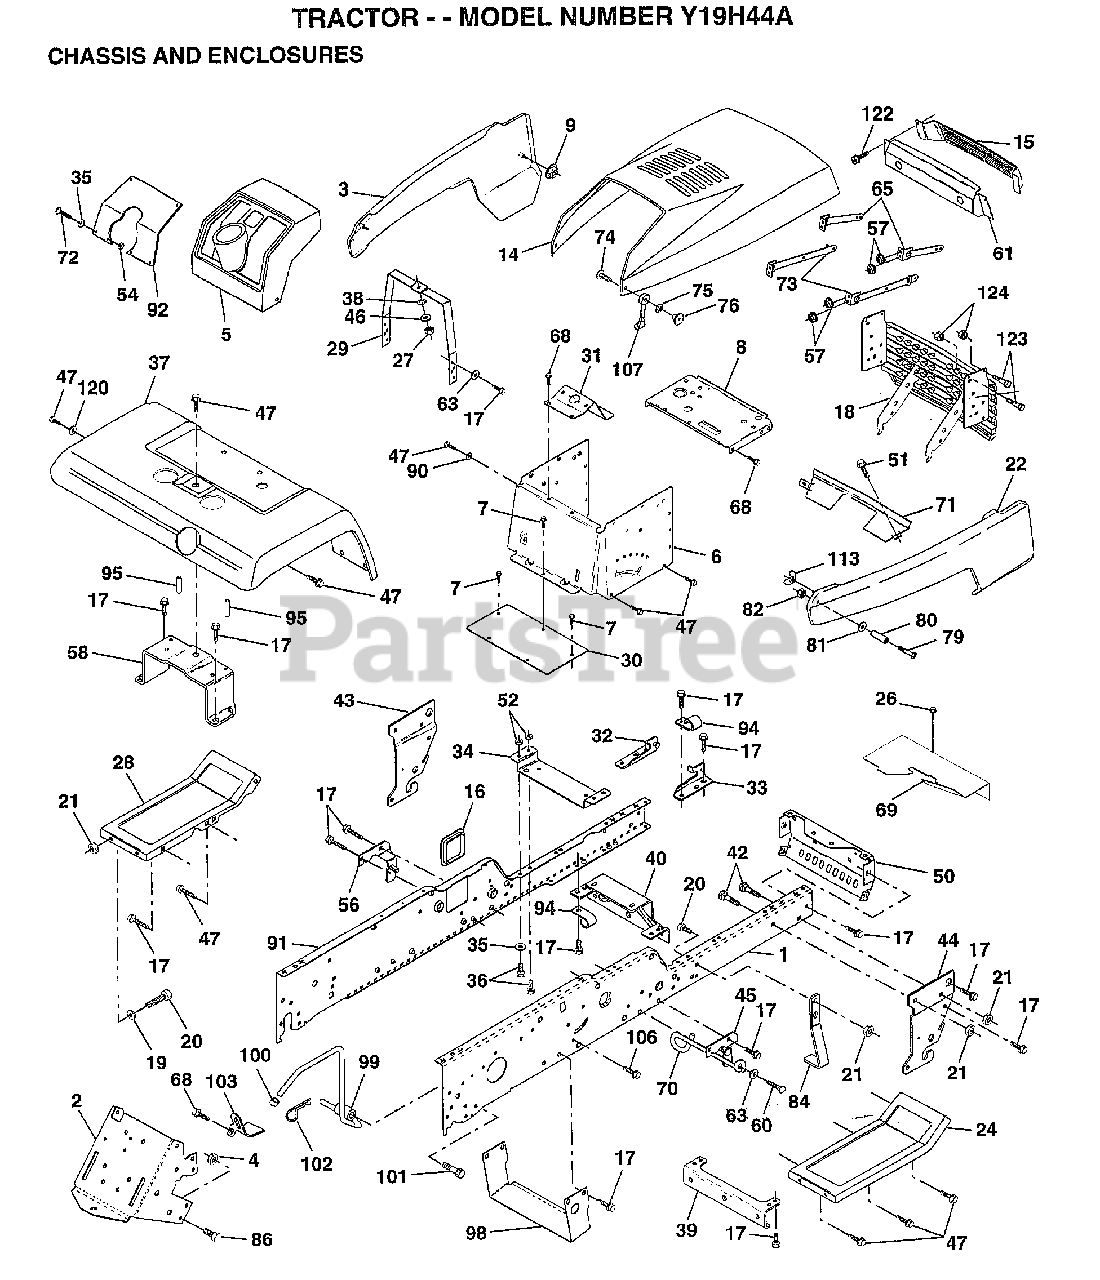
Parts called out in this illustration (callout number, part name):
2	DRAWBAR GT
4	NUT.7/16
5	DASHBOARD BLACK
6	DASH.1PC.LOWER
7	SCREW
8	SUPPORT.DASH.BTRY
9	PAL NUT LT
15	LENS.BAR.CLEAR
16	COVER ACCESS
17	SCREW
19	WASHER
20	BOLT
22	PANEL SIDE RH
24	FOOTREST.RH.LT/GT
26	SCREW
28	FOOTREST.LH.LT/GT
29	DASH.SUPT.YP/HUSQ
30	SADDLE.HYDRO.95
31	BRAKET.SUPT.STEER
32	BRACKET ASM FRAME
33	BRACKET ASM FRAME
34	BRACKET.ENG.SUPT.
35	WASHER
36	BOLT
37	FENDER.PNT.
38	LOCKWASHER
39	BRACKET.AXLE.FRT.
43	BRACKET.SUS.FT.LH
44	BRACKET.SUS.FT.RH
46	WASHER PM
47	SCREW LT
50	BRACKET.CHASSIS.
51	SCREW CRT
57	NUT HXKEP 1/4X20
58	BRKT.ASM.FENDER
60	SCREW
63	WASHER
68	SCREW LT
69	SHIELD.HEAT.MUF
70	GUIDE.BELT.MID.SP
71	STRAP.GRILLE.PNT.
72	SCREW
74	SCREW
75	LOCKWASHER
76	WELDNUT
79	SCREW
80	SPACER LT
81	WASHER
84	STOP.OVER.CENTER
86	BOLT
90	LOCKWASHER
92	PLATE SLKSCR YP
94	CLIP GTV
95	NUT-PUSH YT
98	BRACKET SKID CHAS
99	ROD BYPASS
101	SCREW LT
102	RETAINER M
103	LOCK BYPASS BRKT
107	HOOD LATCH T
120	WASHER HYT
124	NUT
